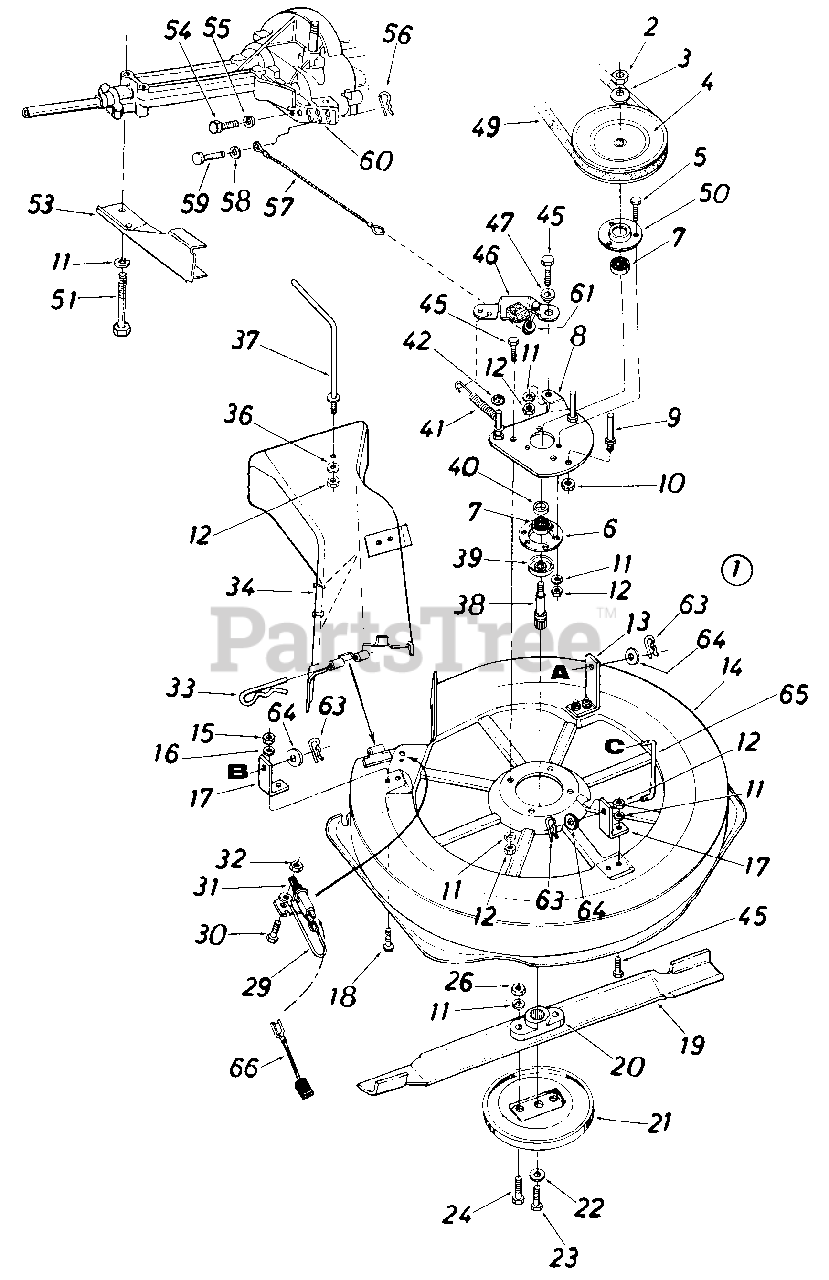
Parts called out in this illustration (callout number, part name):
1	30" R.D. Deck Ass'y. Comp.
2	Hex Jam Nut 5/8-18 Thd.
3	Bell-Wash. .630" I.D. x 1.25"
4	5/8 V-Pulley .75" I.D. x .7"
5	Hex Sems 5/16-18 x .62" Lg.*
6	Brg. Housing 1.85" I.D.
7	Ball Brg..787" I.D.
8	Spindle Mtg. Plate
9	Stud 3/8-16 x 2.75" Lg.
10	Hex Jam Nut 3/8-16 Thd.
11	L-Wash. 5/16" I.D.
12	Hex L-Nut 5/16-18 Thd.
13	Hanger Brkt. 2.92"
17	Hanger Brkt. 1.92"
18	Truss Mach. Scr. 5/16-18 x .75" Lg.*
19	30" High Lift Blade
20	Blade Adapter
21	Scalp Plate
22	L-Wash. 3/8" I.D.
23	Hex Bolt 3/8-24 x 1.0
24	Hex Bolt 5/16-24 x 1.0" Lg.
26	Hex Nut 5/16-24 Thd.
29	Electrical Wire
30	Hex Bolt 1/4-20 x .50" Lg.
31	Safety Switch
32	Hex Nut 1/4-20 Thd.
33	Internal Cotter Pin
34	R.D. Chute Deflector
36	L-Wash. .32" I.D. x .62" O.D.
37	90ø Rod 5/16-18 Thd.
38	Blade Spind le 5.20
39	Bearing Shield
40	Spacer
41	Extension Spring
42	Push Speed Nut
45	Hex Bolt 5/16-18 x .75"*
46	Blade Brake Brkt. Ass'y.
47	Shoulder Spacer .500" Dia.
49	"V"-Belt 1/2" x 52" Lg.
50	Open Brg. Housing
51	Hex Bolt 5/16-18 x 2.75"
53	Lower Outside Belt Guard
54	Hex Bolt 1/4-20 x .62" Lg.
55	L-Wash. 1/4" I.D.
56	Int. Cot. Pin 5/16" Dia.
57	Brake Cable 11.75" Lg.
58	Fl-Wash. .281" I.D. x .50"
59	Clevis Pin 1/4" Dia.
60	Lower Inside Belt Guard
61	Cap Speed Nut 1/4" Rod
63	Int. Cotter Pin 1/2" Dia.
64	Fl-Wash. .531" I.D. x .930"
65	Deck Link 3.9" Lg.
66	Wire Lead
